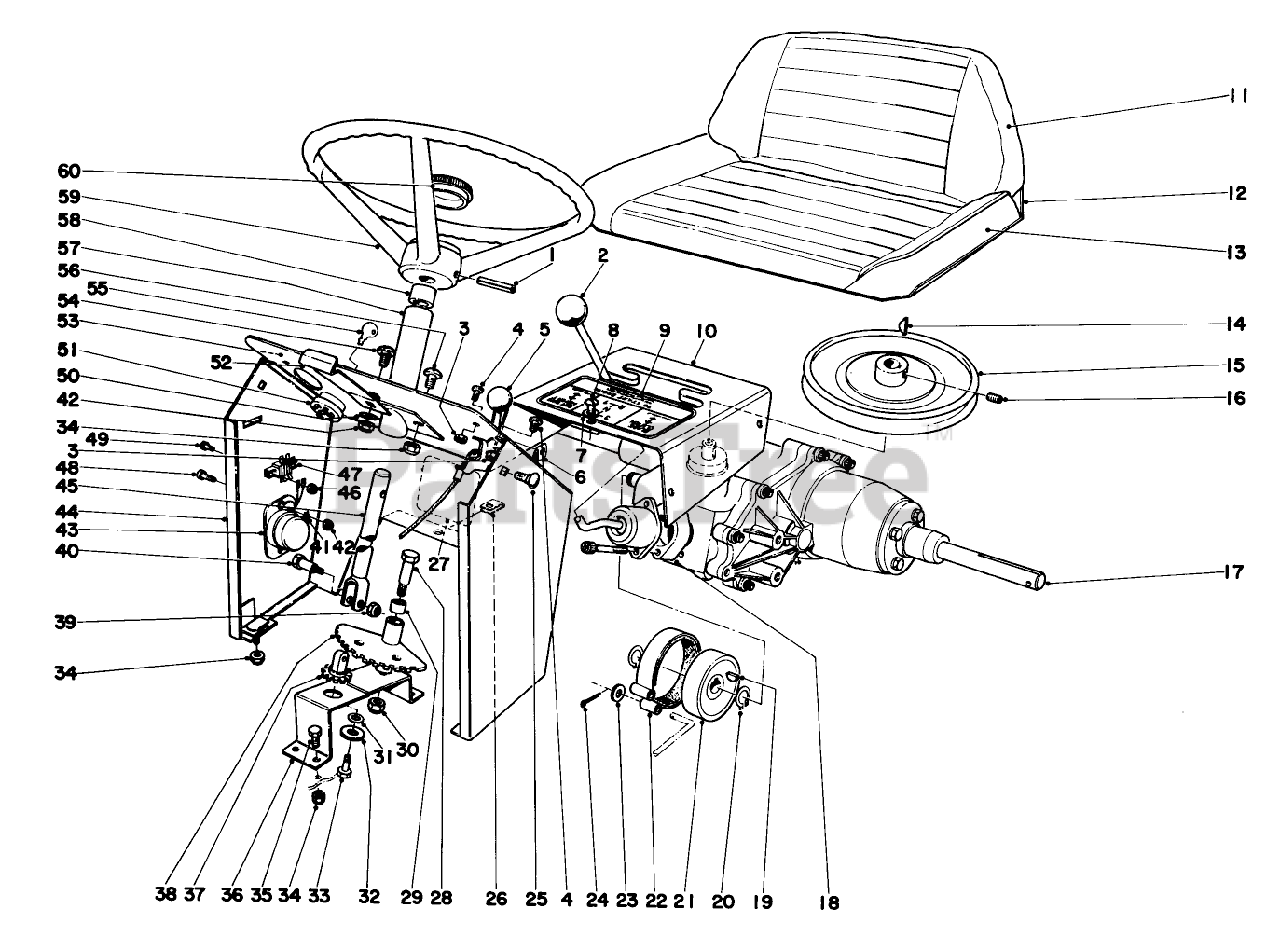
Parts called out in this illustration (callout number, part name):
1	PIN-ROLL
3	NUT-KEPS
5	Throttle Control
6	Strap Cable Tie
7	WASHER-LOCK
8	SCREW
9	Decal-Shift Pattern
10	Tunnel
11	Seat Back
12	Frame-Seat
13	Seat Cushion
14	KEY-WOODRUFF
15	Pulley
16	Set Screw
17	Transaxle
18	Extension Shift Housing
19	KEY-WOODRUFF
20	RING-SNAP, EXTERNAL
21	Brake Drum
22	Brake Band
23	WASHER-PLAIN
24	PIN-COTTER
25	BOLT-CARR
26	SPEED NUT
27	Decal-Caution
28	Shoulder Bolt
29	BUSHING
30	NUT-LOCK
31	Spacer
32	Washer
33	SCREW-HH
34	NUT-LOCK, CONE
35	SCREW-HH
36	Bracket
37	Pinion Steering
38	Gear Steering (Incl. Ref. #29)
39	NUT-HEX
40	Screw Shoulder
41	WASHER-LOCK/EXT
42	NUT-LOCK, CONE
43	Cover-Center
45	Steering Shaft
46	NUT-LOCK, NI
47	Terminal Block
49	SCREW-HEAD, PAN
50	WASHER-FLAT
51	STARTER SWITCH
52	Hood Latch
53	Decal Dash
54	Carriage Bolt
55	Key
56	Round Head Screw
57	Steering Tube (Incl. Ref. #58)
58	BUSHING
59	Steering Wheel
60	Steering Wheel Cap
